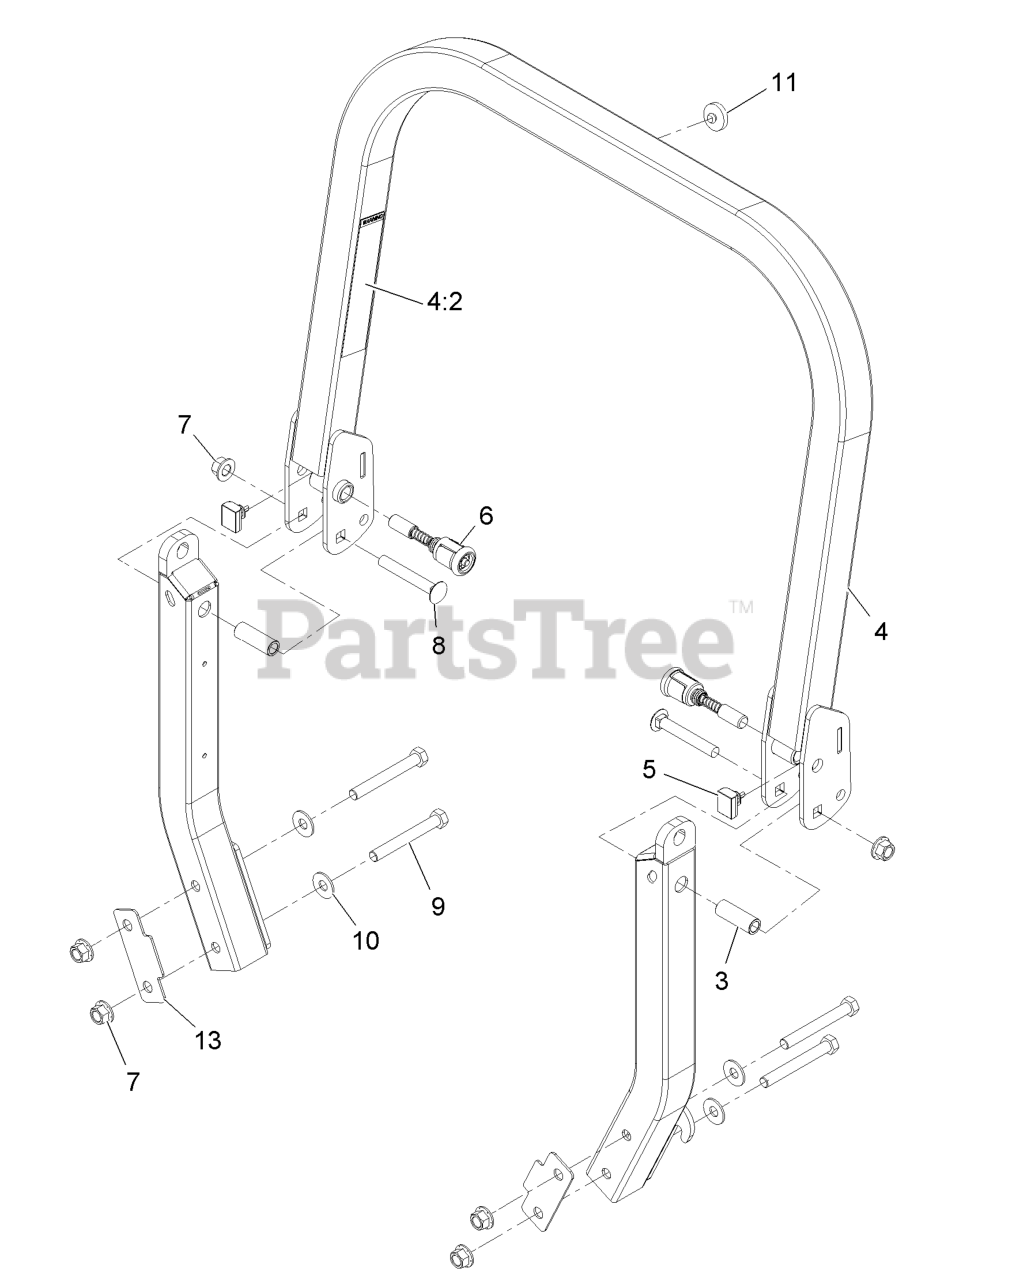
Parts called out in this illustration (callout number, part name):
4	UPPER ROPS ASM
4:2	DECAL-WARNING, FOLDING RO
5	BUMPER-ROPS
6	PIN-SPRING
7	Nut-Lock 1/2-13
8	SCREW-CARR
9	SCREW-HH
10	WASHER-SPRING
11	BUMPER-PUSH-IN, RUBBER
